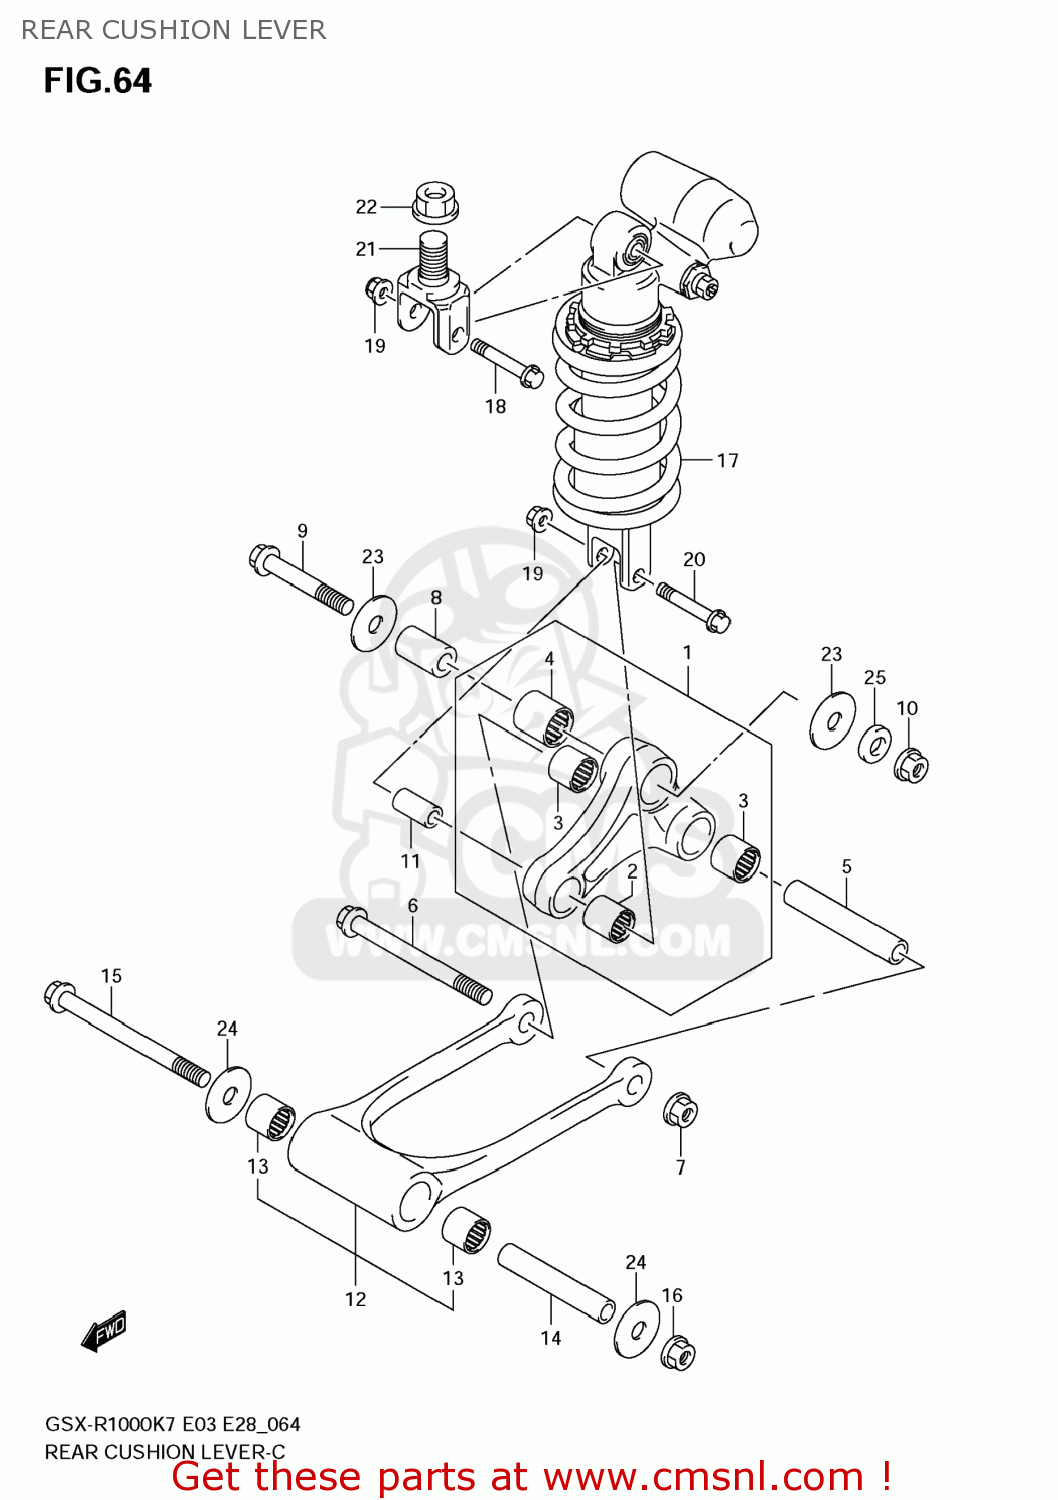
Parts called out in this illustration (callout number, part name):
1	LEVER SET,RR CUSHION
2	BEARING(17X24X26)
3	BEARING(17X24X25)
4	BEARING(20X27X32)
5	SPACER,RR CUSHION ROD
6	BOLT,RR CUSHION LEVER LWR
7	NUT
8	SPACER,RR CUSHION LEVER FR
9	BOLT,RR CUSHION LEVER FR
10	NUT
11	SPACER,RR CUSHION LEVER
12	ROD SET,RR CUSHION LEVER
13	BEARING(17X24X25)
14	SPACER,RR CUSHION LEVER CTR
15	BOLT,RR CUSHION ROD
16	NUT
17	ABSORBER ASSY,RR SHOCK(YELLOW)
18	BOLT(10X55)
19	NUT
20	BOLT(10X55)
21	BRACKET,RR SHOCK ABSORBER UPR
22	NUT
23	WASHER(12X34X1)
24	WASHER,RR CUSH LVR CTR,L
25	WASHER(12X25X4)
